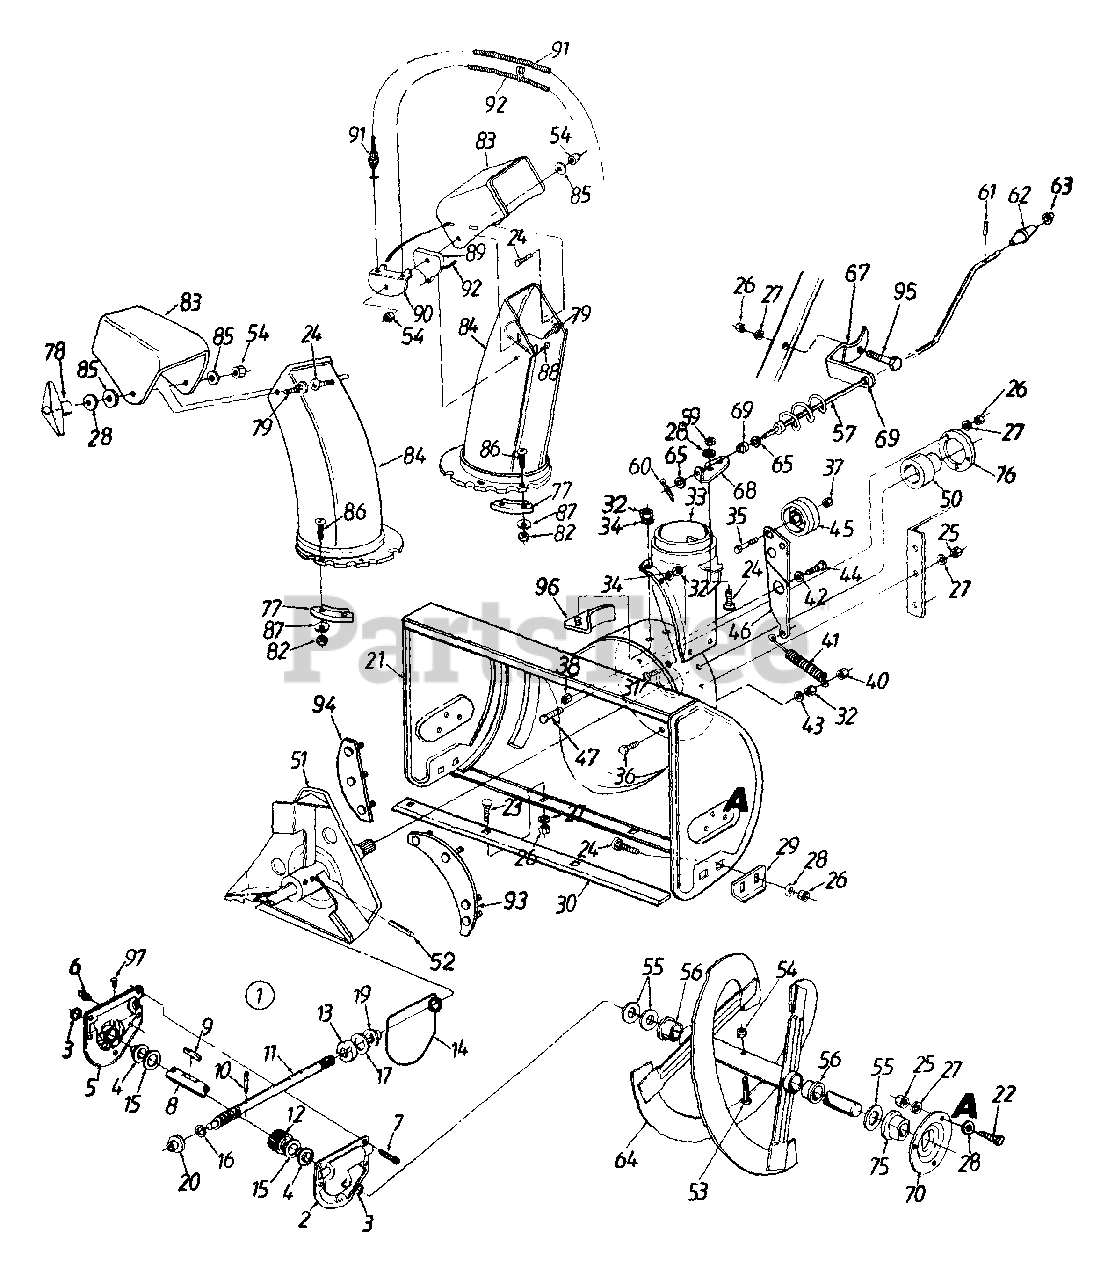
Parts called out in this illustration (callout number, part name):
1	Worm Drive Ass'y. Comp. (616E)
1	Worm Drive Ass'y. Comp. (646F)
1	Auger Gear Box Ass'y. (666H)
2	Reducer Housing - L.H.
3	Oil Seal
4	Flange Bearing .75" I.D.
5	Reducer Housing - R.H.
6	Grease Fitting
7	Hex TT-Tap Scr. 1/4-20 x .75" Lg.
8	24" Auger Shaft (616E)
8	26" Auger Shaft (646F)
8	30" Auger Shaft (666H)
9	#61 Hi-Pro Key 3/16" x 5/8" Dia.
10	Spiral Pin 1.25" Lg.
11	Impeller Shaft
12	Worm Gear
13	Thrust Collar
14	Oil Seal
15	Fl-Wash. .76" I.D. x 1.5" O.D.
16	Fl-Wash. .5" I.D. x 1" O.D.
17	Fl-Wash. .76" I.D. x 1.49" O.D.
19	Flange Bearing .75" I.D.
20	Flange Bearing .503" I.D.
23	Carriage Bolt 5/16-18 x .62" Lg.
24	Carriage Bolt 5/16-18 x .75" Lg.
25	Hex Nut 5/16-24 Thd.
26	Hex Nut 5/16-18 Thd.
27	L-Wash. 5/16" I.D.
28	Bell-Wash. .345" I.D. x .88" O.D.
30	24" Shave Plate (616E)
30	26" Shave Plate (646F)
30	30" Shave Plate (666H)
31	Truss Mach. Scr. 1/4-20 x .5" Lg.
32	Hex Nut 1/4-20 Thd.
33	Chute Adapter
34	Spring Washer 1/4" I.D.
35	Hex Bolt 3/8-24 x 1.5" Lg. (Gr. 5)
36	Hex Bolt 1/4-20 x .75" Lg. (Gr. 5)
37	Hex Ins. L-Nut 3/8-24 Thd.
38	Hex Top L-Nut 3/8-16 Thd.
40	Hex L-Nut 1/4-20 Thd.
41	Ext. Spring 3.6" Lg.
42	Fl-Wash. 5/8" I.D. x 1.25"
43	L-Wash. 1/4" I.D.
44	Shld. Bolt .625" Dia. x .170" Lg.
45	Fl-Idler 2.75" O.D.
46	Auger Idler Brkt.
47	Hex Bolt 5/16-18 x 5/8" Lg.
50	Ball Bearing .75" I.D.
51	Blower Fan Ass'y.
52	Spiral Pin 1.5" Lg
53	Shear Bolt 5/16-18 x 1.5" Lg.
54	Hex Cent. L-Nut 5/16-18 Thd.
55	Fl-Wash .76" I.D. x 1.49"
56	Flange Bushing .8" I.D.
57	Chute Crank Ass'y.
59	Hex Ins. L-Nut 5/16-18 Thd.
60	Cotter Pin 3/32" Dia x 75"
61	Roll Pin 1/8" Dia. x 63" Lg
62	Chute Crank Knob
63	Push Nut
64	Spiral Ass'y. - L.H. (616E)
64	Spiral Ass'y. - R.H.
64	Spiral Ass'y. - L.H. (646F)
64	Spiral Ass'y. - L.H. (666H)
65	Fl-Wash. 385" I.D. x .62" O.D.
69	Plastic Bushing .38" I.D
70	Bearing Housing
75	Plastic Bearing w/Flats
76	Bearing Housing
77	Chute Flange Keeper
78	Knob (616E)
79	Carriage Bolt 5/16-18 x 1.5" Lg.
82	Hex L-Nut 1/4-20 Thd.
83	Upper Chute (616E)
83	Upper Chute (646F & 666H)
84	Lower Chute
85	Fl-Wash. .344" I.D. x 1.125"
86	Truss Mach. Scr 1/4-20 x .75" Lg.
87	Fl-Wash. 1/4" I.D.
88	Hex AB-Tap Scr 1/4 x .62" Lg. (646F)
89	Cable Guide (646F & 666H)
91	Chute Control Cable (646F & 666H)
92	Chute Control Cable w/Clip (646F)
95	Hex Bolt 5/16-18 x 1.5" Lg.
96	Chute Reinforcement
